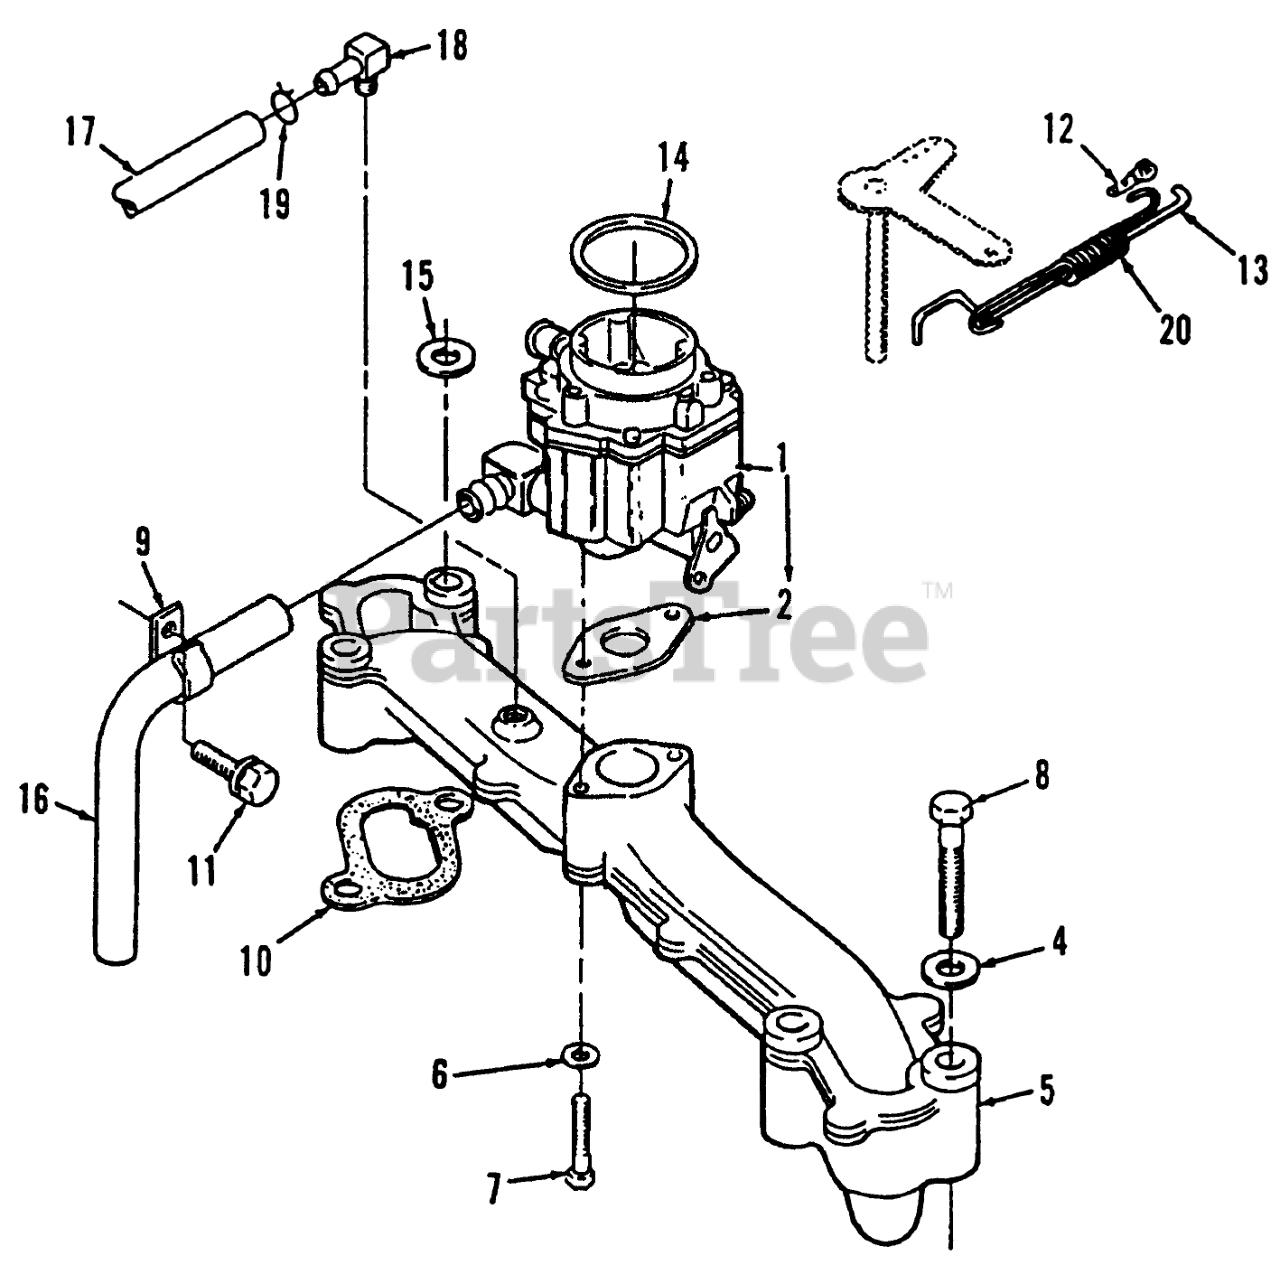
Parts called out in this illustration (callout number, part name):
1	Carburetor (Includes Mounting Gasket, Elbow, & O-Ring)
2	GASKET-CARBURETOR
4	WASHER-FLAT
5	MANIFOLD
6	Bolt
7	Bolt
9	Clip
10	GASKET
11	Screw
13	GOVERNOR CONTROL ROD
15	FLAT WASHER
16	FIXED-JET
17	HOSE-RUBBER, BREATHER
18	Fitting
19	CLAMP-HOSE, BREATHER
20	Spring-Governor Rod
